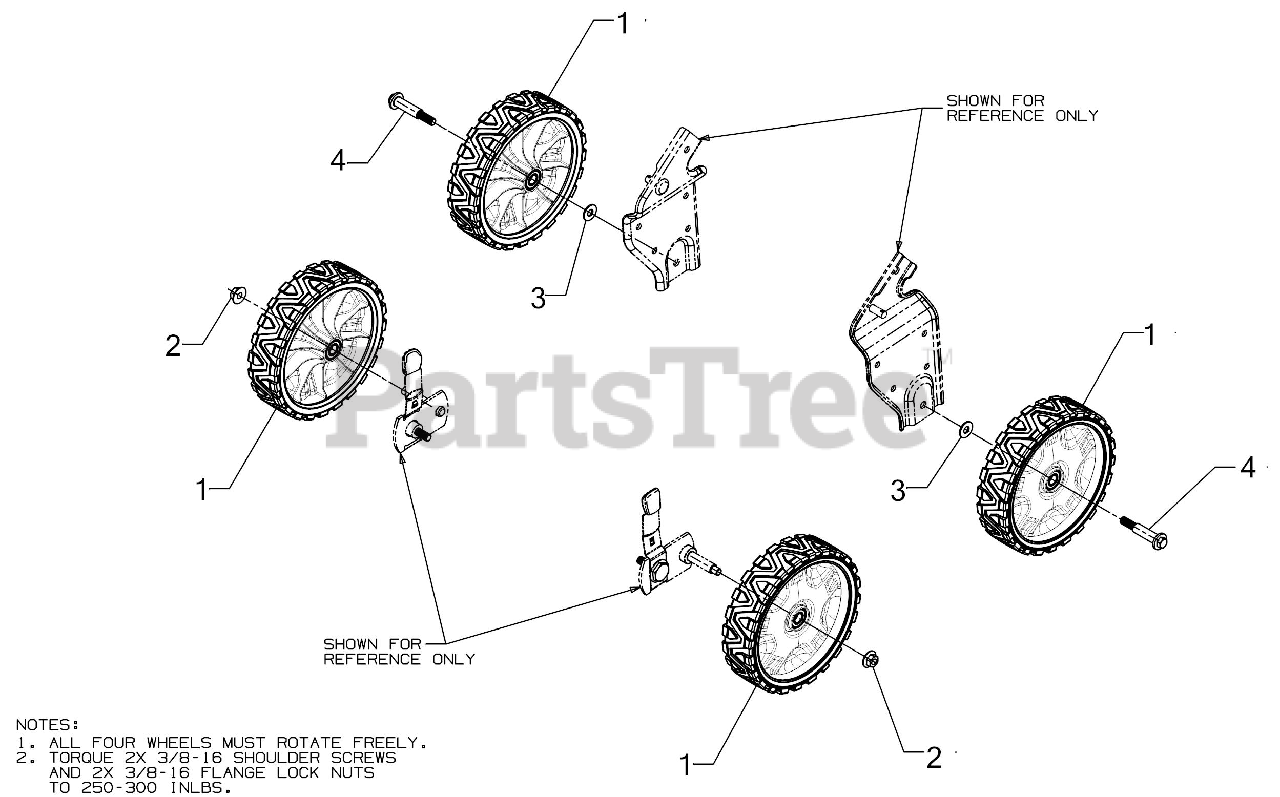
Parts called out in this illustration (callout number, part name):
1	WHEEL ASSEMBLY (8 x 2)
2	FLANGE LOCK NUT
3	BELL WASHER .400 ID x .88 x .060
4	SHOULDER SCREW .496X1.605 3/8-16
